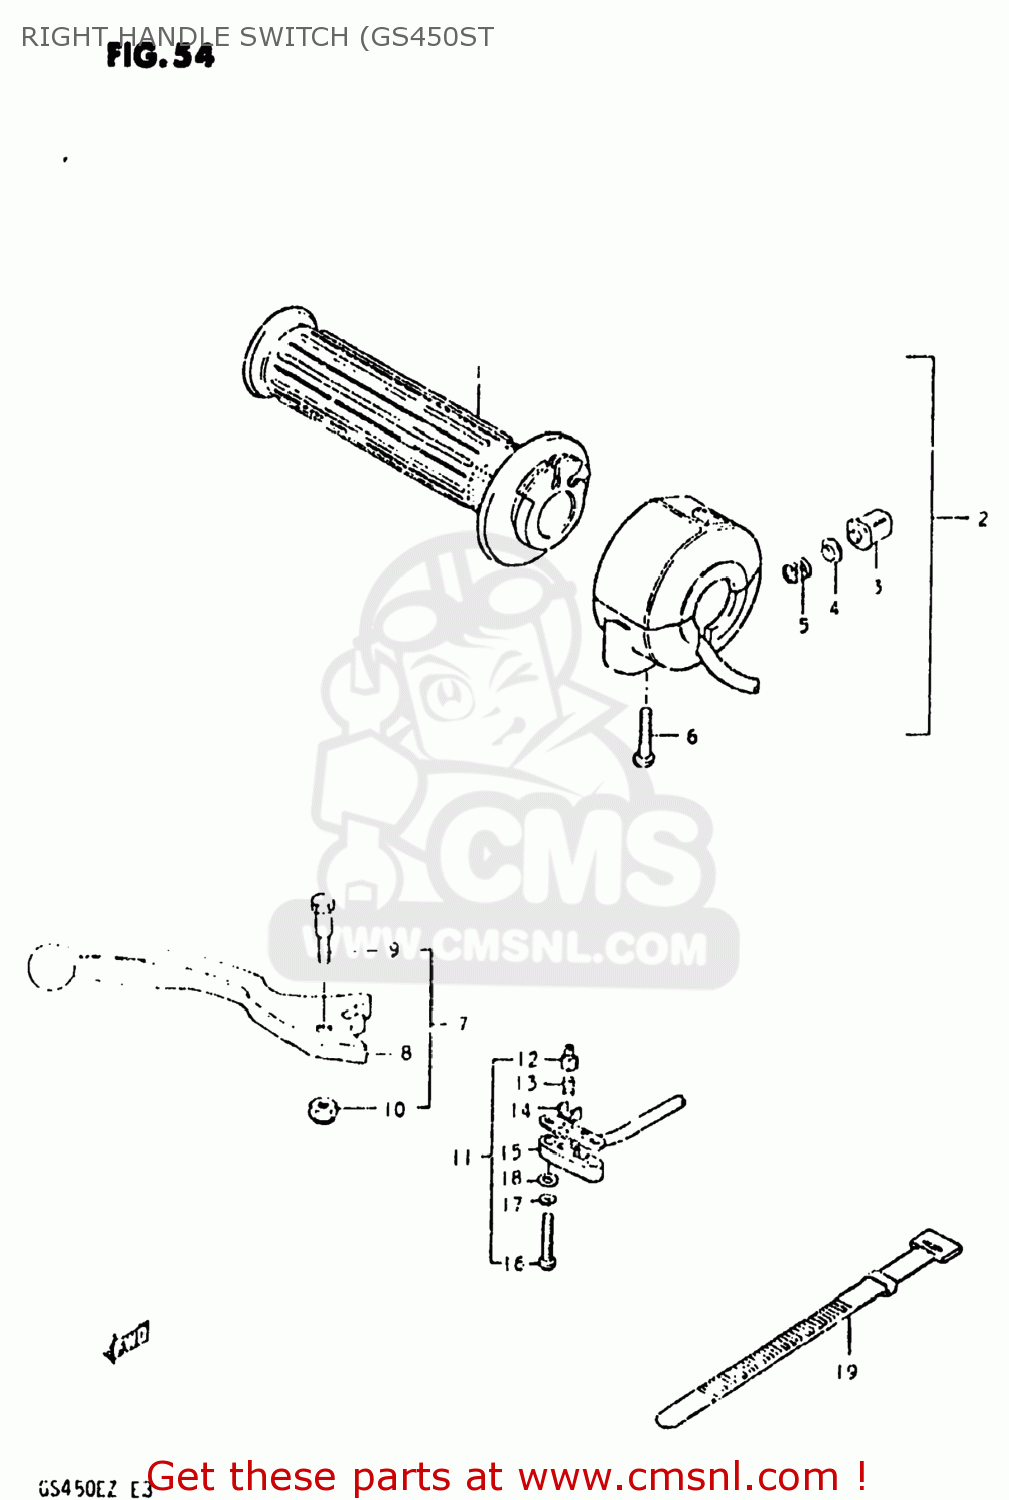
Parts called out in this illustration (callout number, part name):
1	GRIP,THROTTLE
2	CASE ASSY,THROTTLE
3	BUTTON,HORN
4	CONTACT
5	SPRING,STARTER BUTTON
6	SCREW
7	LEVER ASSEMBLY,BRAKE
8	LEVER,BRAKE
9	BOLT
10	NUT 6MM
11	SWITCH ASSEMBLY
12	HOLDER
13	SPRING
14	PLATE
15	COVER,FR BK TERMINAL BASE
16	SCREW
17	LOCK WASHER
18	WASHER
19	CLAMP(L:120)
